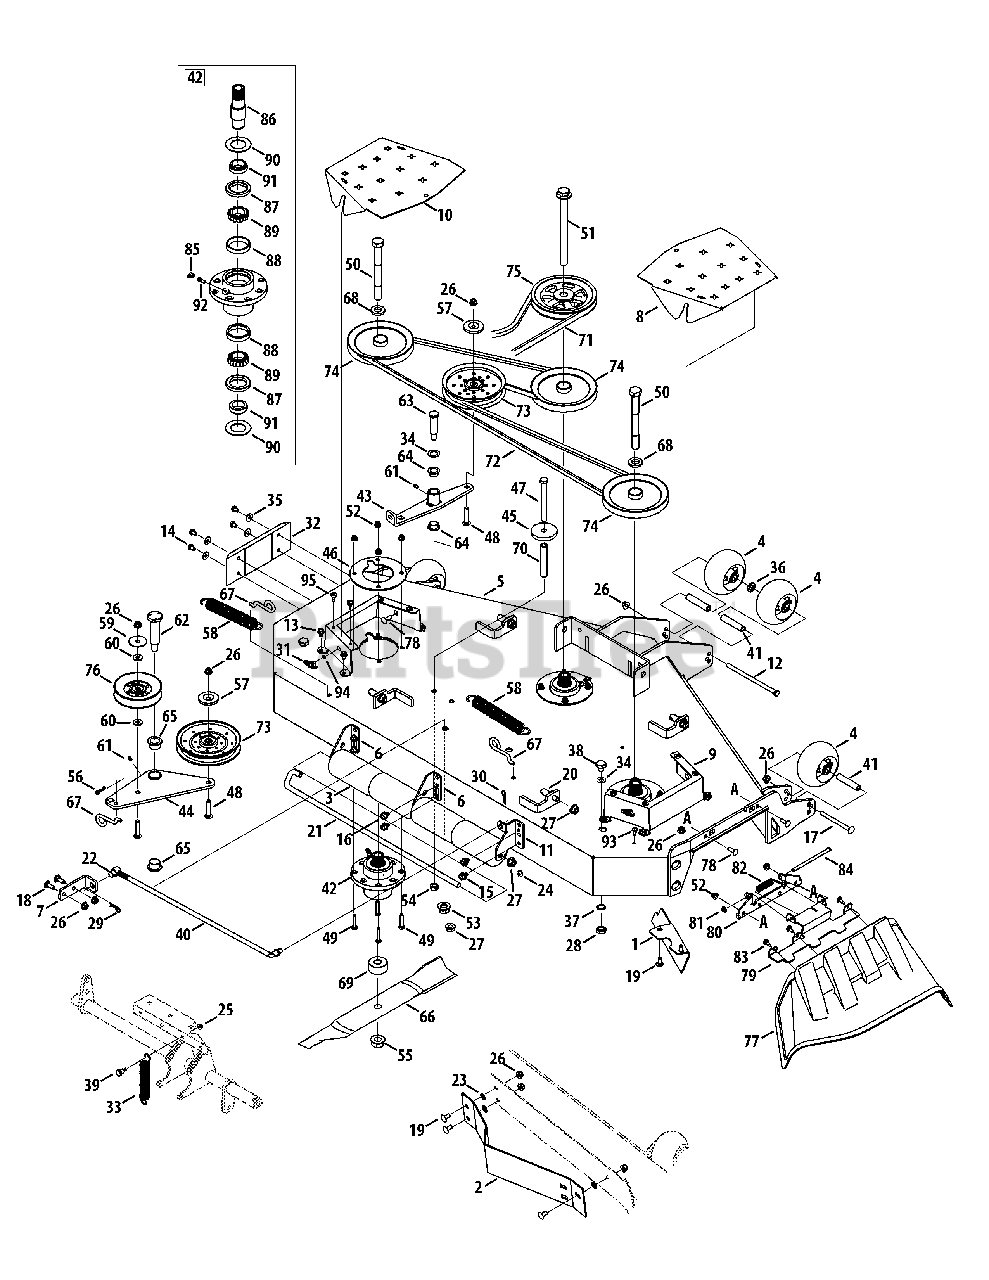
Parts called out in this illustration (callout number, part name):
2	Baffle, 60" Adjustment
3	Anti-Scalp Roller Assembly
4	Complete Wheel, 5.00 Dia.
6	Rear Roller Mount Bracket
7	Deck Stabilizer Mount Bracket
8	Deck Belt Cover, RH
9	Deck Belt Cover Bracket
10	Deck Belt Cover, LH
11	Rear Roller Bracket, RH
12	Hex Cap Screw, 3/8-16 x 7.25
13	Screw, 5/16-18 x .500
14	Screw, 5/16-18 x .500
15	Screw, 3/8-16 x .750
16	Screw, 3/8-16 x .500
17	Carriage Screw, 3/8-16 x 4.50
18	Carriage Bolt, 3/8-16 x 1.00
19	Carriage Bolt, 3/8-16 x .750
20	Pin, 1/2-13 x .625 x 1.2
21	J-Hook w/ Threaded Roller
23	Push Nut, 3/8
24	Jam Lock Nut, 3/8-16
25	Nut, 1/4-20, Flangelock
26	Nut, 3/8-16, Flangelock
27	Nut, 1/2-13, Flangelock
28	Hex Nut, M16-1.5
29	Click Pin, .092 x 1.64
30	Internal Cotter Pin
32	Skid Guard Plate
33	Extension Spring, .969 x 6.180
34	Washer, .793 x 1.24 x .06
35	Flat Washer, .343 x .880 x .062
36	Flat Washer, .632 x 1.00 x .160
37	Lock Washer, 17 x 23.8 x 1.95
38	Plug, Screw, M16-1.5
39	Shoulder Bolt, .437 x .50, 1/4-20
40	Deck Support Rod, 1/2" Dia.
41	Wheel Spacer
42	Spindle Assembly
43	Deck Idler Arm
44	Idler Assembly
45	Spacer, .5375 x 2.75 x .375
46	Spindle Support Plate
47	Hex Cap Screw, 1/2-13 x 5.00
48	Screw, 3/8-16 x 2.00
49	Bolt, 5/16-18 x 1.25
50	Hex Cap Screw, 3/4-16 x 7.00
51	Hex Cap Screw, 3/4-16 x 9.00
52	Nut, 5/16-18, Flangelock
53	Nut, 5/8-18, Flangelock
54	Nut, 1/2-13, Hexlock
55	Nut, 3/4-16, Flangelock
56	Bow Tie Cotter Pin
57	Pulley Cap
58	Extension Spring, 1.248 x 8.5
59	Washer, .406 x 1.92 x .060
60	Washer, .406 x 1.00 x .105
61	Grease Fitting
62	Shoulder Bolt, 1.0 x 3.15, 5/8-18
63	Shoulder Bolt, .750 x 2.23, 1/2-13
64	Flange Bearing, .75 x .52
65	Flange Bearing, 1.00 x .75
66	Hi-Lift Blade, 21.0
67	Spring Rod Hook
68	Spacer, .812 x .218
69	Spacer, .760 x 2.00 x .925
70	Spacer, .405 x .75 x 3.875
73	Idler Pulley
74	Spindle Pulley
75	Drive Pulley
76	Idler Pulley
77	Discharge Chute Assembly
78	Carriage Bolt, 5/16-18 x 1.00
81	Push Cap
82	Torsion Spring
83	Shoulder Screw, 1/4-20
84	Chute Rod
85	Grease Fitting, 45 degree, 1/4-28
86	Spindle Shaft
87	Seal, Oil
88	Cup Bearing
89	Cone Bearing
90	Washer, 1.50 x 2.52 x .075
91	Ring, Seal
92	Straight Adapter Fitting
93	Hex Flange Screw, 1/4-20 x .500
94	Speed Nut, .3125
95	Bumper, .62 Dia. x .3
